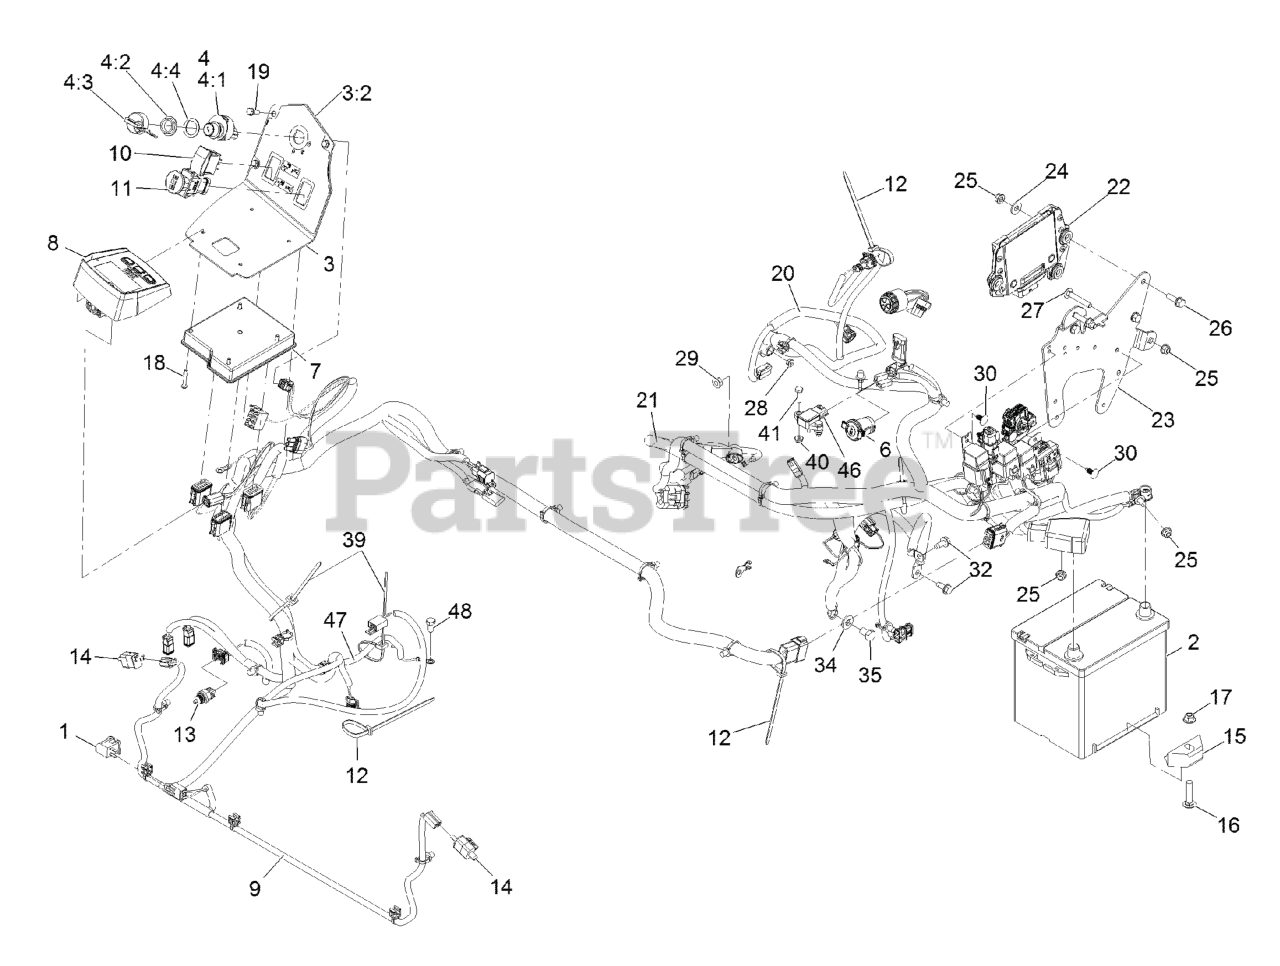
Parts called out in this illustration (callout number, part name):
1	SWITCH-BAIL
2	Battery-Dry
3	Console ASM
3:2	DECAL-CONTROL PANEL
4	IGNITION SWITCH ASM
4:1	Switch-Ignition
4:2	NUT-MOUNTING
4:3	IGNITION KEY SET
4:4	WASHER-BACKUP
6	PORT-POWER, 12V
7	Module-Mcu
8	Module, Ldu
9	HARNESS-WIRE
11	SWITCH-PTO, SEALED
12	TIE-PLASTIC
13	SENSOR-TEMPERATURE
15	RETAINER-BATTERY
16	SCREW-CARR
17	NUT-HF, NI
18	SCREW-PPH
19	SCREW-HWH
20	HARNESS-WIRE
21	CABLE-BATTERY
22	ECU ASM
23	BRACKET-MOUNT, ECU
24	WASHER-FLAT
25	NUT-HF, NI
26	SCREW-HHF
27	BOLT-CARR
30	PLUG-PLASTIC
32	Screw-HWH 5/16-18 X 3/4 Tf
34	WASHER-BELLEVILLE
35	SCREW-HH
39	TIE-CABLE
41	SCREW-HH
46	SENSOR-ATM
47	HARNESS-WIRE, JUMPER
48	BOLT
